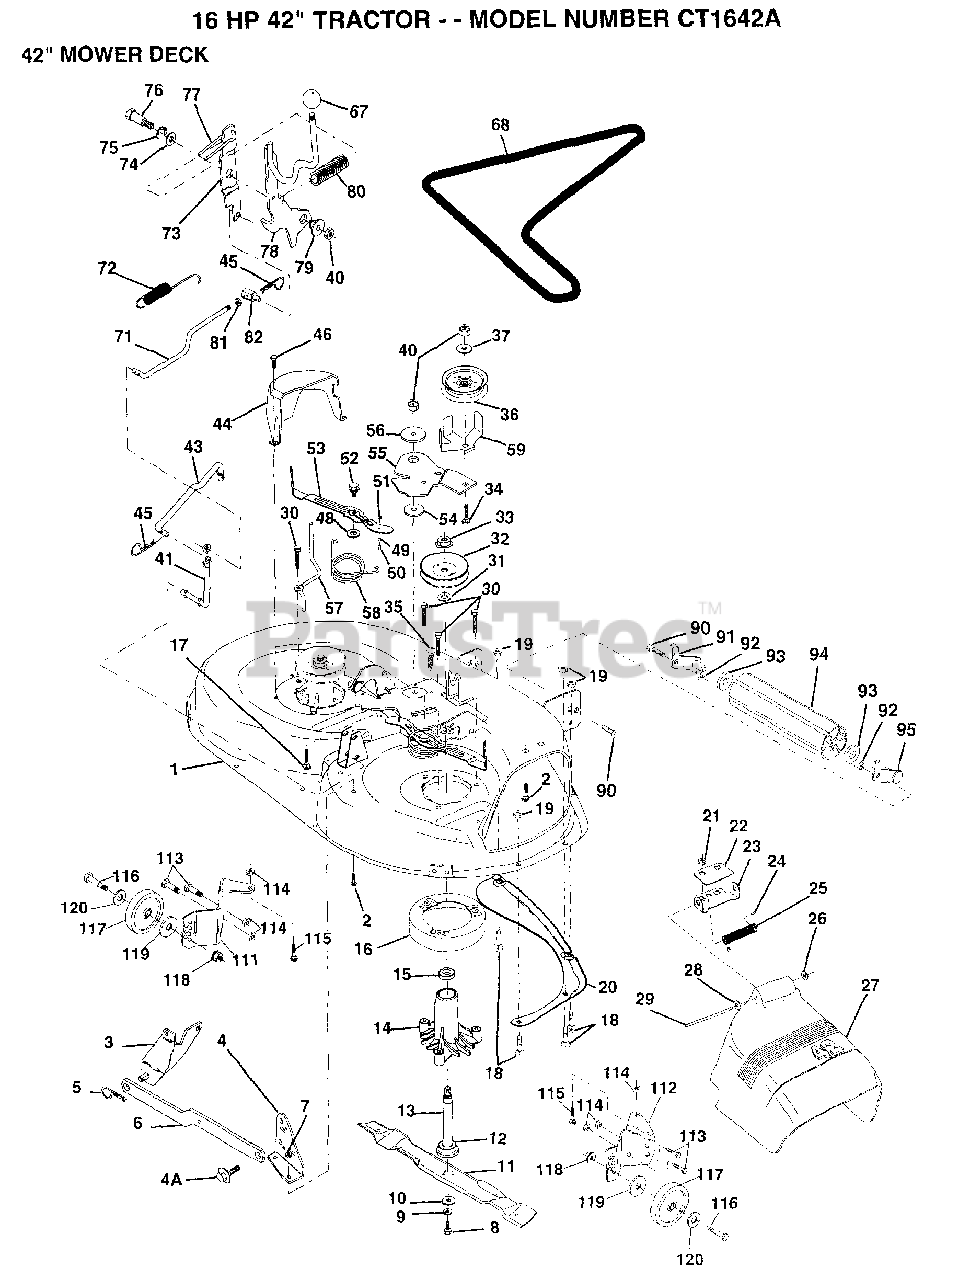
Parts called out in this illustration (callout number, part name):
2	BOLT
3	BRKT ASM SWAY BAR
4	BRKT DECK SW BAR
4A	BOLT SHD 5/16-18
7	NUT
8	BLADE BOLT
10	WASHER.HARD.BLADE
11	"BLADE.42"" MULCHER"
12	BEARING.BALL
14	HSG ASM MANDREL
15	BEARING
16	STRIPPER RND MWR
17	BOLT RDHD 3/8-16
18	BOLT
19	NUT
21	NUT
22	STIFFENER BRKT
23	DEFLECTOR BRKT
24	CAP-SLEEVE LT
25	SPRING TORSION
26	NUT PUSH M
27	DEFLECTOR.SHIELD
28	WASHER
29	HINGE ROD
31	WASHER
34	BOLT
35	XMAS TREE FASTNER
36	FLAT IDLER PULLEY
37	WASHER
41	PIVOT ROD
43	ROD CLUTCH W/NIBS
44	GUARD MAND LH BLK
45	RETAINER M
46	SCREW.1/4-20X5/8
48	HARD SMALL WASHER
50	SHOULDER BOLT
51	LOCKNUT
52	BOLT.SHLD.5/16-18
53	BRAKE PAD ARM ASM
54	HARDENED WASHER
56	SPACER RETAINER
57	KEEPER BELT LH 42
58	SPRING TORSN BRAK
59	GUARD IDLER TUV
68	BELT-V MWR 82.625
71	ROD CLUTCH 38/42
72	RETURN SPRING
73	CLUTCH ARM SECOND
74	WASHER
75	RING
76	SHOULDER BOLT
77	SPRING KEEPER
78	LEVER ASM CLT PRM
79	BUSHING
81	NUT
82	TRUNION ADJ
83	CONTROL KNOB LT
90	BOLT
93	WASHER
113	BOLT
116	BOLT M
117	WHEEL.GAGE.BLK.PL
118	LOCKNUT
119	WASHER
120	WASHER
